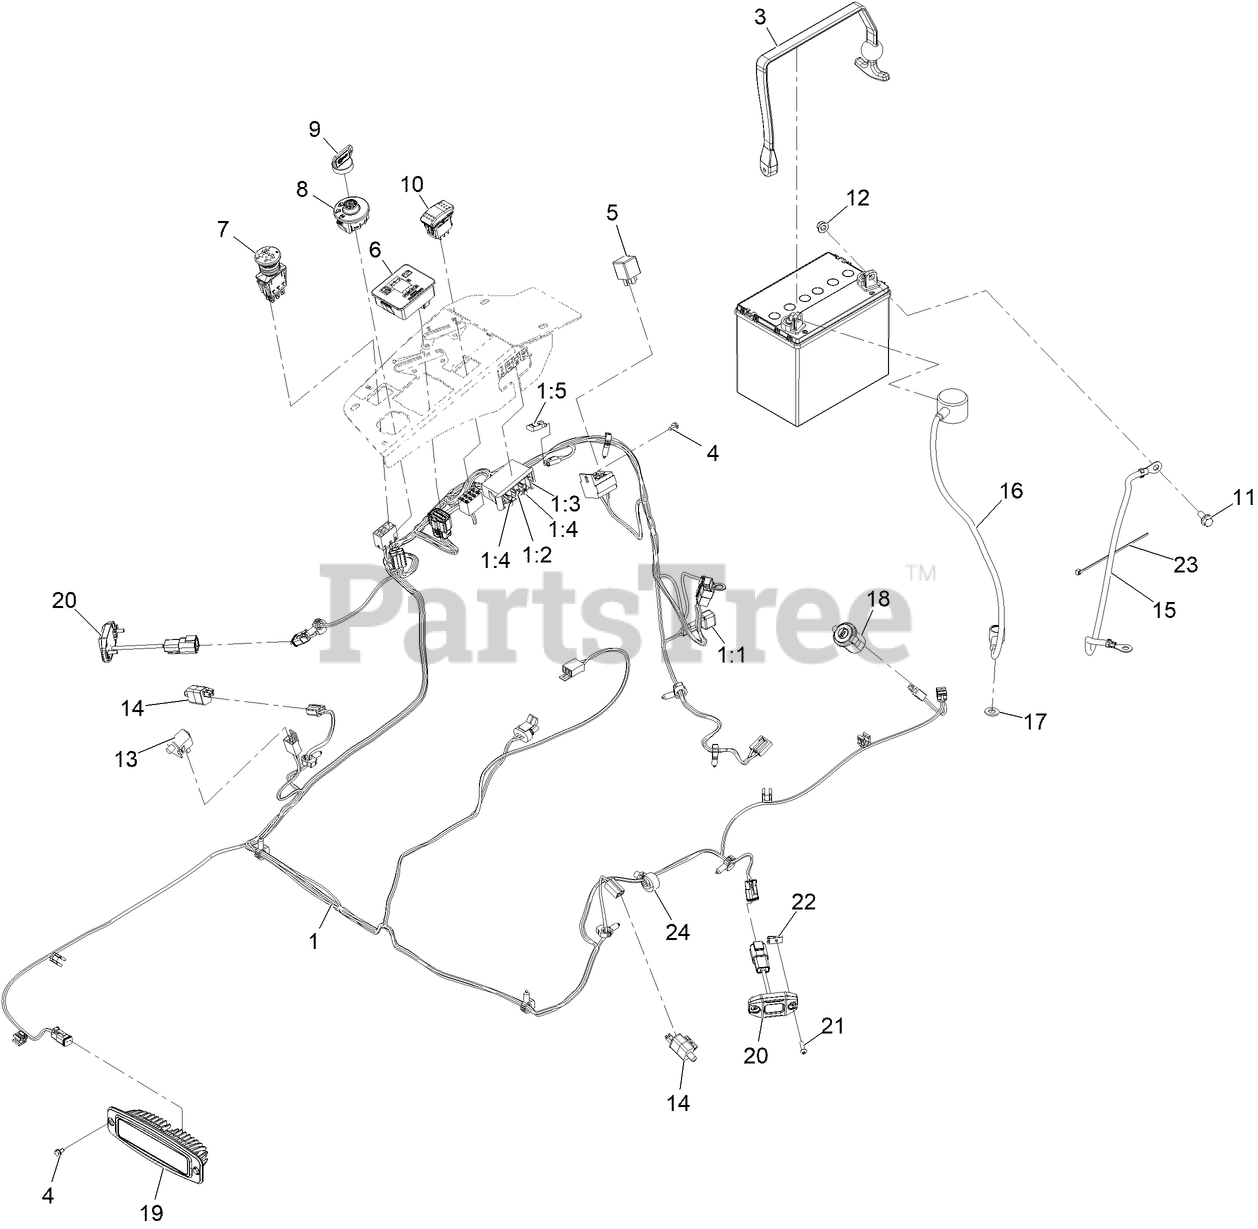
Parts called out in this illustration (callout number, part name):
1	HARNESS-MAIN LRX CARB
1:2	FUSE-BLADE, 10 AMP
1:3	FUSE-BLADE, 15 AMP
1:4	FUSE-BLADE, 25 AMP
1:5	CAP-PLUG
3	Strap-Bungee
4	SCREW-HWH
6	FUEL/HOUR METER ASM
7	SWITCH, PTO 10A
8	SWITCH-IGNITION
9	KEY-IGNITION
11	SCREW-HHF
12	NUT-HF, NI
13	SWITCH-BAIL
15	CABLE-BATTERY, NEGATIVE
16	CABLE-BATTERY, POSITIVE
17	WASHER-FLAT
18	PORT-POWER, USB
19	MOUNT-FLUSH, LIGHT
20	LIGHT-ROCK
21	Screw-HSBH
22	Nut-Speed
23	TIE-CABLE
24	CLIP-TIE
